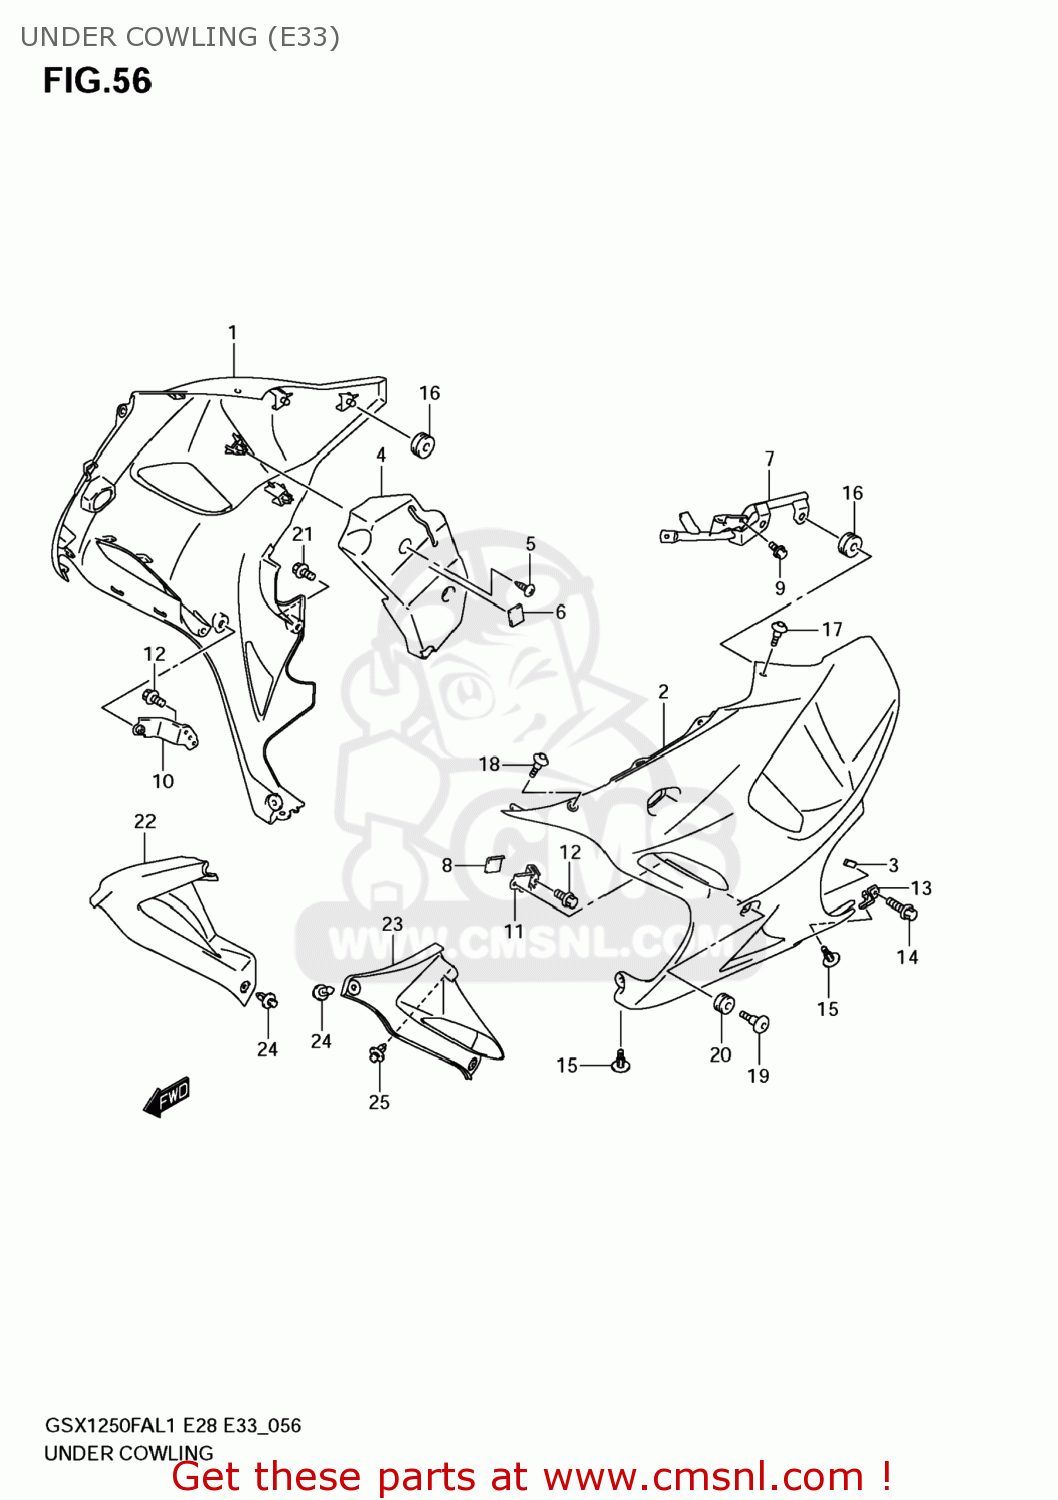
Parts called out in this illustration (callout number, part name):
1	COWLING,UNDER,R
2	COWLING,UNDER,L
3	CUSHION,LICENSE PLATE
4	PROTECTOR,COWLING UNDER,R
5	SCREW
6	CUSHION,UNDER COWL ENG,R NO.1
7	BRACKET,COWLING FITTING,L
8	PROTECTOR,COWLING UNDER
9	BOLT
10	BRACKET,UNDER COWLING FR,R
11	BRACKET,UNDER COWLING FR,L
12	BOLT
13	BRACKET,UNDER COWLING LWR,L
14	BOLT(6X25)
15	CLIP
16	CUSHION
17	SCREW(5X16)
18	SCREW(5X13)
19	SCREW(6X20)
20	CUSHION
21	SCREW(6X12)
22	COWLING,UNDER INNER,R
23	COWLING,UNDER INNER,L
24	CLIP
25	CLIP
